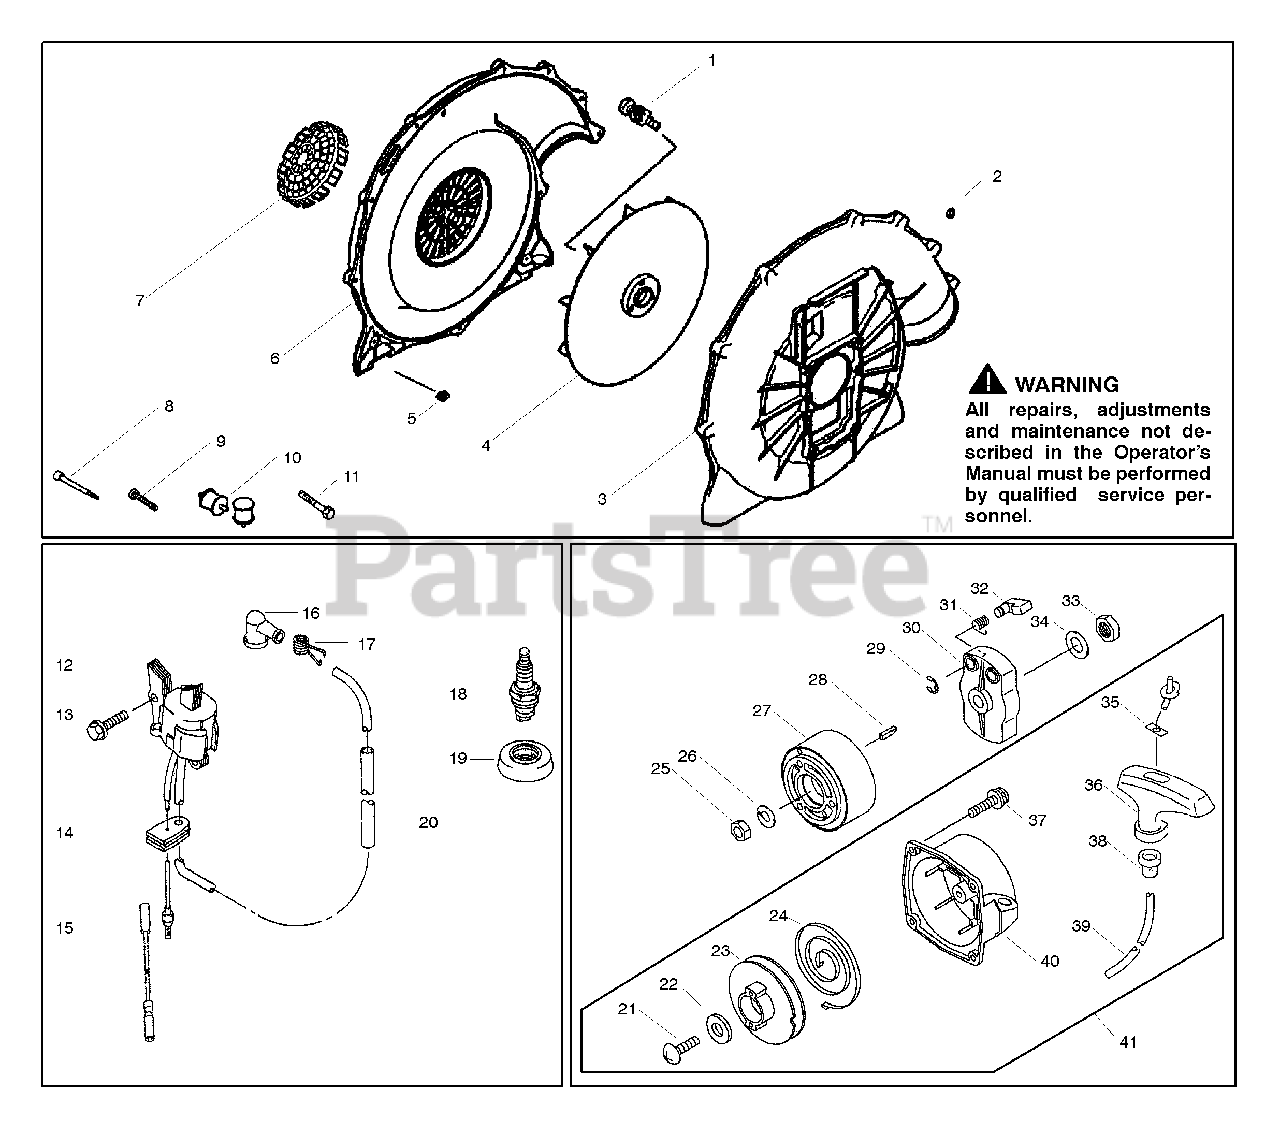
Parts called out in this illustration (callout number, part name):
1	Bolt-Lock
2	Nut-Nylon
3	Case-Fan
6	Case-Fan
7	Cover-Fan
8	Screw-Socket
9	Screw-Tapping m5x20
10	Isolator-Vibro Rubber
11	Bolt-Lock
12	Assy-Ignition Coil
15	Wire-Lead
16	Cap-Spark Plug
17	Terminal
18	Plug-Spark NGK (BPMR7A)solid
20	Tube-6x7.4x300
23	Reel-Starter Recoil
24	Spring-Recoil
25	Nut-Hex (fine)
27	Flywheel
29	Ring-Snap
30	Pulley-Starting
31	Spring-Return
32	Pawl-Recoil Starter
33	Nut-Hex (fine)
34	W-Plain-S
35	Plate-Recoil Starter
36	Grip-Recoil Starter
38	Guide-Rope
39	Rope 3.8x850
40	Case-Recoil Starter
41	Starter-Recoil
